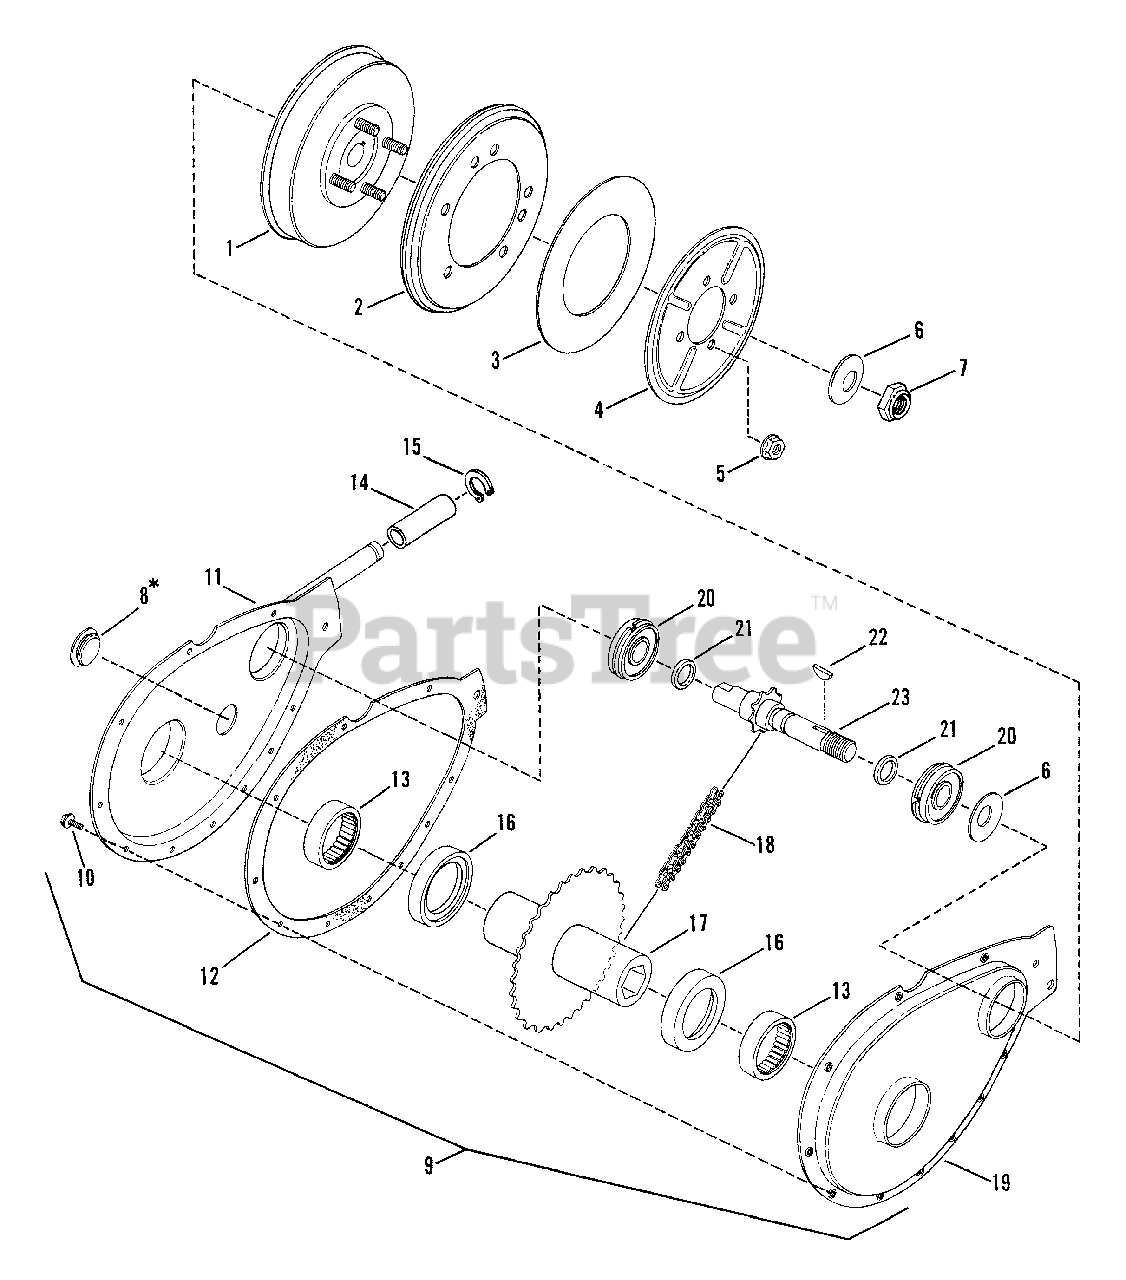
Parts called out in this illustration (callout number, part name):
1	HUB, Driven Disc
2	DISC, Driven
3	WASHER, Thrust
4	PLATE
5	NUT, 5/16-18 Hex Flange Lock
6	WASHER, Belleville
7	NUT, 5/8-18 Hex Lock
8	PLUG, Oil Fill & Check
9	ASSEMBLY, Chain Case
10	SCREW, #10-24 x 1/2" Hex Washer Self-Tap (Torx)
11	CASE, Sprocket
12	GASKET, Case Cover
13	BEARING, Needle
14	ROLLER
15	RING, Retaining
16	WASHER, Nylon Thrust
17	ASSEMBLY, Hub & Sprocket
18	CHAIN
19	COVER, Chain Case
20	BEARING, Ball
21	"O" RING
22	KEY, 1/8 x 5/8" Woodruff
23	ASSEMBLY, Sprocket & Shaft
